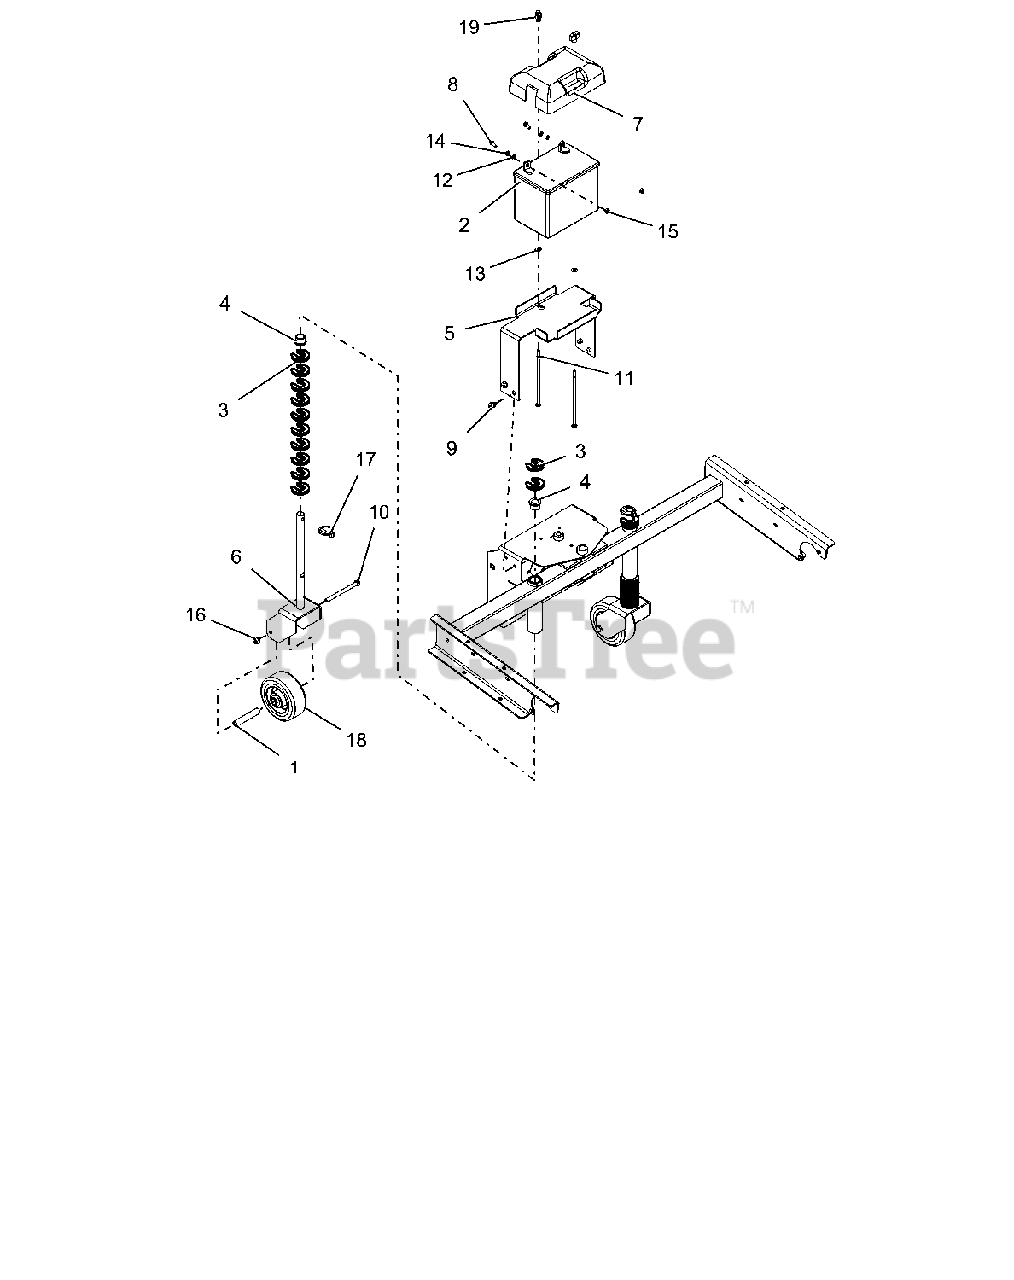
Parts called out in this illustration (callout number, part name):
1	SPACER, CASTER WHEEL
2	BATTERY, 300 CCA 10U1L
3	CLIP-HOC FIXED
4	BUSHING, FLANGE .75X.75X1.0
5	TRAY, BATTERY - POWER BRUSH
6	FORK, CASTER
7	COVER, BATTERY
8	BLT-HEX .25-20X.75 GR5 YWZC
9	SCR-TAP .38-16X.50 HWH TR YWZ
10	BLT-HEX .38-16X4.50 GR5 YWZC
11	BLT-RDHDSQNK .25-20X7.00 G2YZ
12	WSHR-LK .25X.062 REG YWZC
13	WSHR-FL-STL.281X.62X.065 YWZC
14	WSHR-FL-STL .265X.50X.087YWZC
15	NUT-HEX .25-20 YWZC
16	NUT-LK-TOP-FLG .38-16 YWZC
17	PIN, 1/4X1-9/16 LYNCH
18	WHEEL, CASTER - 5"OD
19	KNOB, WING - .25-20 UNC
